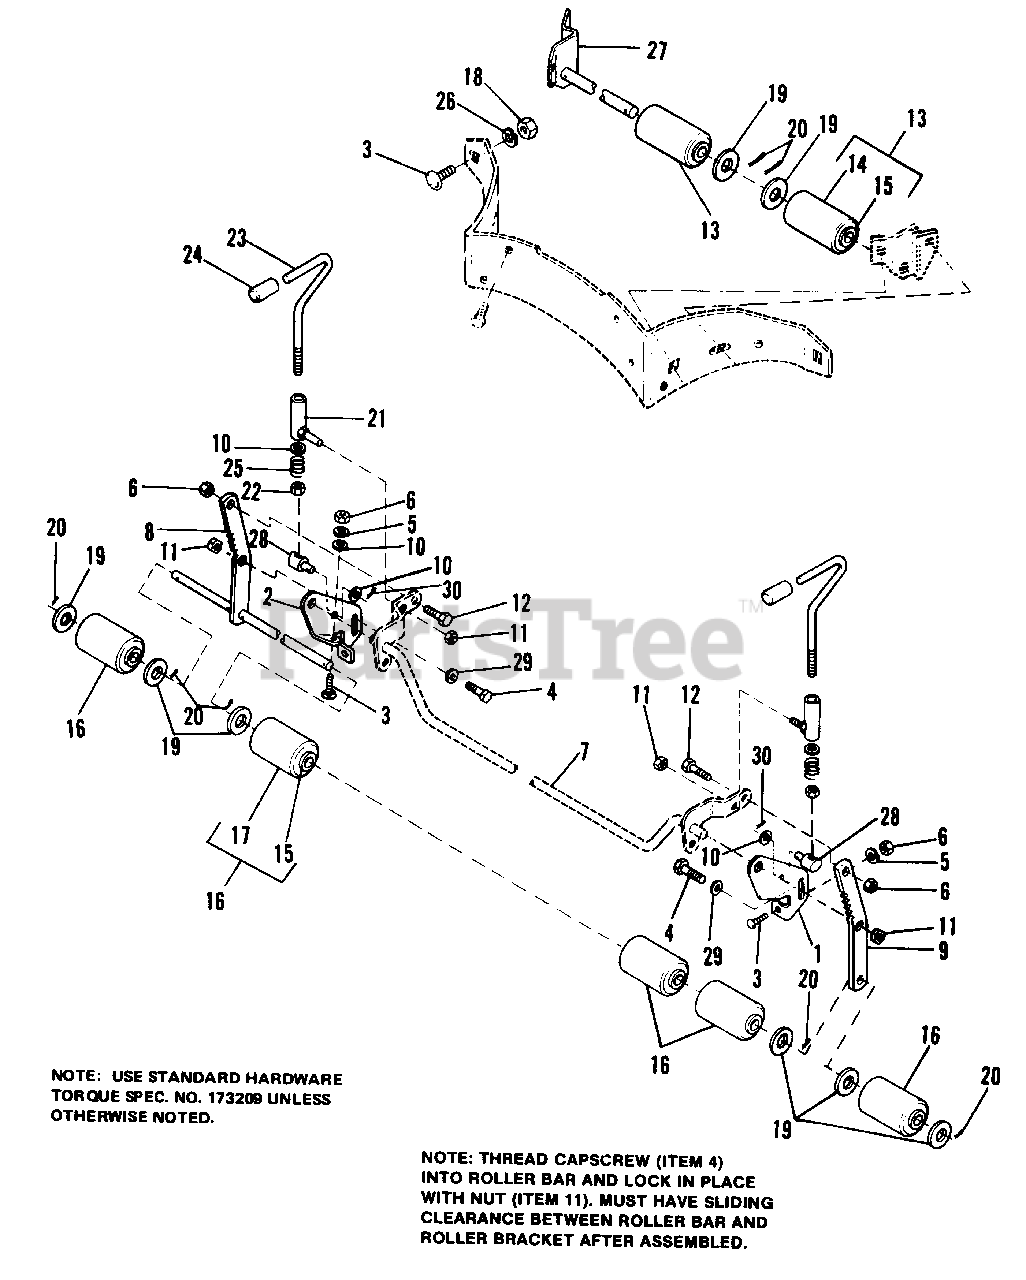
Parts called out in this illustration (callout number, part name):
1	BRACKET, Roller, L.H.
2	BRACKET, Roller, R.H.
3	BOLT, Rd. Hd., 3/8-16 x 3/4
4	CAPSCREW, Hex, Hd., 3/8-16 x 1
5	LOCKWASHER, Spring, 3/8
6	NUT, Hex, 3/8-16
7	ARM ASSY, Rocker
8	SHAFT ASSY, Roller
9	BAR SUB-ASSY, Roller
10	WASHER, Plain, 3/8
11	NUT, Hex, Full Lock, 3/8-16
12	CAPSCREW, Hex Hd., 3/8-16 x 1
13	ROLLER SUB-ASSY
14	ROLLER
16	ROLLER ASSY
17	ROLLER
18	NUT, Hex, 5/16-18
19	WASHER, Plain, 5/8
20	PlN,Cotter, 3/16 x 1
21	SOCKET ASSY
22	NUT, Hex, Jam, 3/8-16
23	HANDLE, Adj.
24	GRIP
25	SPRING, Adj. Screw
26	LOCKWASHER, 5/16
27	BRACKET & SHAFT ASSY
29	WASHER, Plain, 5/16
30	PIN, Cotter, 3/32 x 5/8
